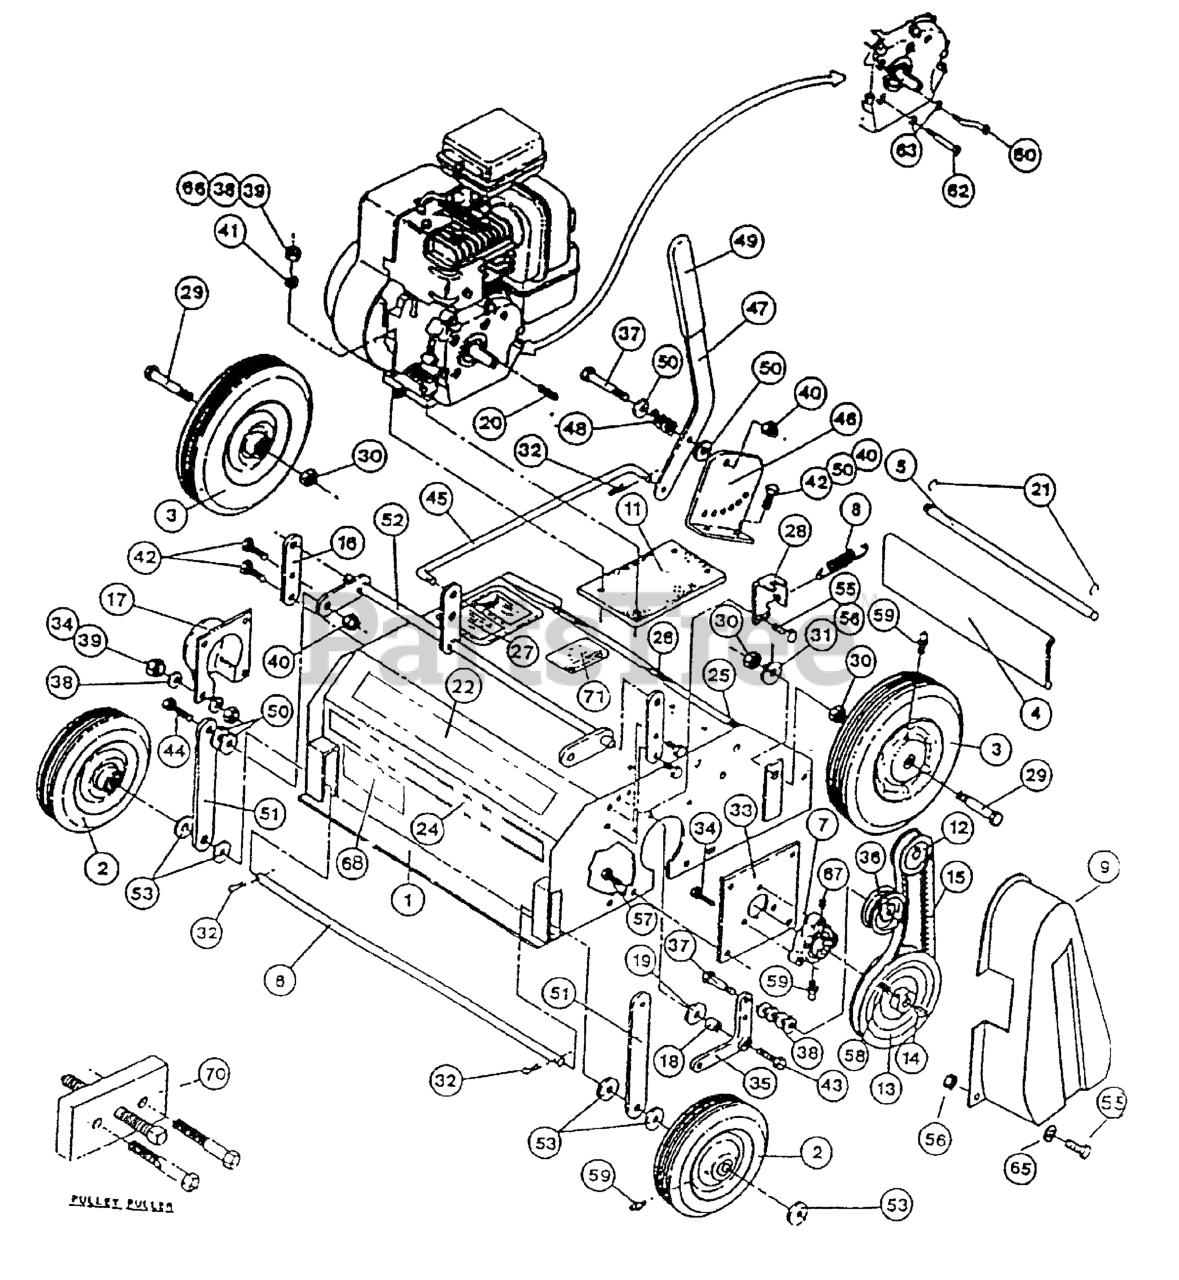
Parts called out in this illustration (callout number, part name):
1	RAKE BODY W/DECALS
1	Slicer Body w/Decals
2	WHEEL, FRONT
4	DEFLECTOR SHIELD
5	DEFLECTOR ROD
6	FRONT AXLE
7	BEARING, FLANGED
8	EXTENSION SPRING
9	BELT GUARD
11	PAD, ENGINE
12	PULLEY, ENGINE DRIVE
13	PULLEY, MAIN SHAFT
14	KEY, #9 WOODRUFF
15	BELT, DRIVE RAKE/SLICER DFS
17	SHAFT GUARD
18	BEARING, ONLITE RAKE/DT
20	KEY 3/16 SQUARE X 1 3/4
21	RETAINING RING 5/16
22	DECAL, HUSQVARNA 17.5"
24	Decal, DT20
25	DECAL, CPSC
26	DECAL, WARNING
27	DECAL, ADJUSTING
28	BRACKET, CABLE
29	BOLT, AXLE 5/8-11 X 4
30	NUT JAM 5/8-11 HEX
31	LOCKWASHER 5/8
32	RP_COTTER PIN 1/8 X 3/4
34	BOLT, TAP 5/16-18
35	BELL CRANK
36	IDLER PULLEY
37	HCS 3/8C X 2
38	WASHER 5/16 FLAT
39	NUT 5/16 NYLOC
40	NUT 3/8-16 NYLOC
41	WASHER.LOCK.HVY.HLCL.SPR.5/16
42	HCS 3/8-16X1.GRD.5.ZD
43	HCS 3/8C X 1 1/2
44	HCS 3/8C X 1 1/4 GR5
45	LINKAGE ARM
46	ADJUSTMENT GAUGE
47	ADJUSTING LEVER
48	COMPRESSION SPRING
50	WASHER 3/8 FLAT
52	HEIGHT ADJ ROD
53	WASHER 1/2 FLAT
55	HCS 1/4C X 5/8
56	NUT.1/4-20.HEX.NYLOC.ZD
57	SCREW 5/16C X 1 HEX CAP
58	SET SCREW 5/16 NYLOC
59	ZERK
60	BELT GUIDE, OFFSET
62	SCREW, 5/16-24 X 2-3/4 HED CAP
63	NUT JAM 5/16F HEX
65	WASHER 1/4 FLAT
66	HCS 5/16C X 1 3/4
67	SET SCW #10-32 X 1/4
68	DECAL, NASCAR
70	PULLEY PULLER
71	DECAL, PROP. 65
